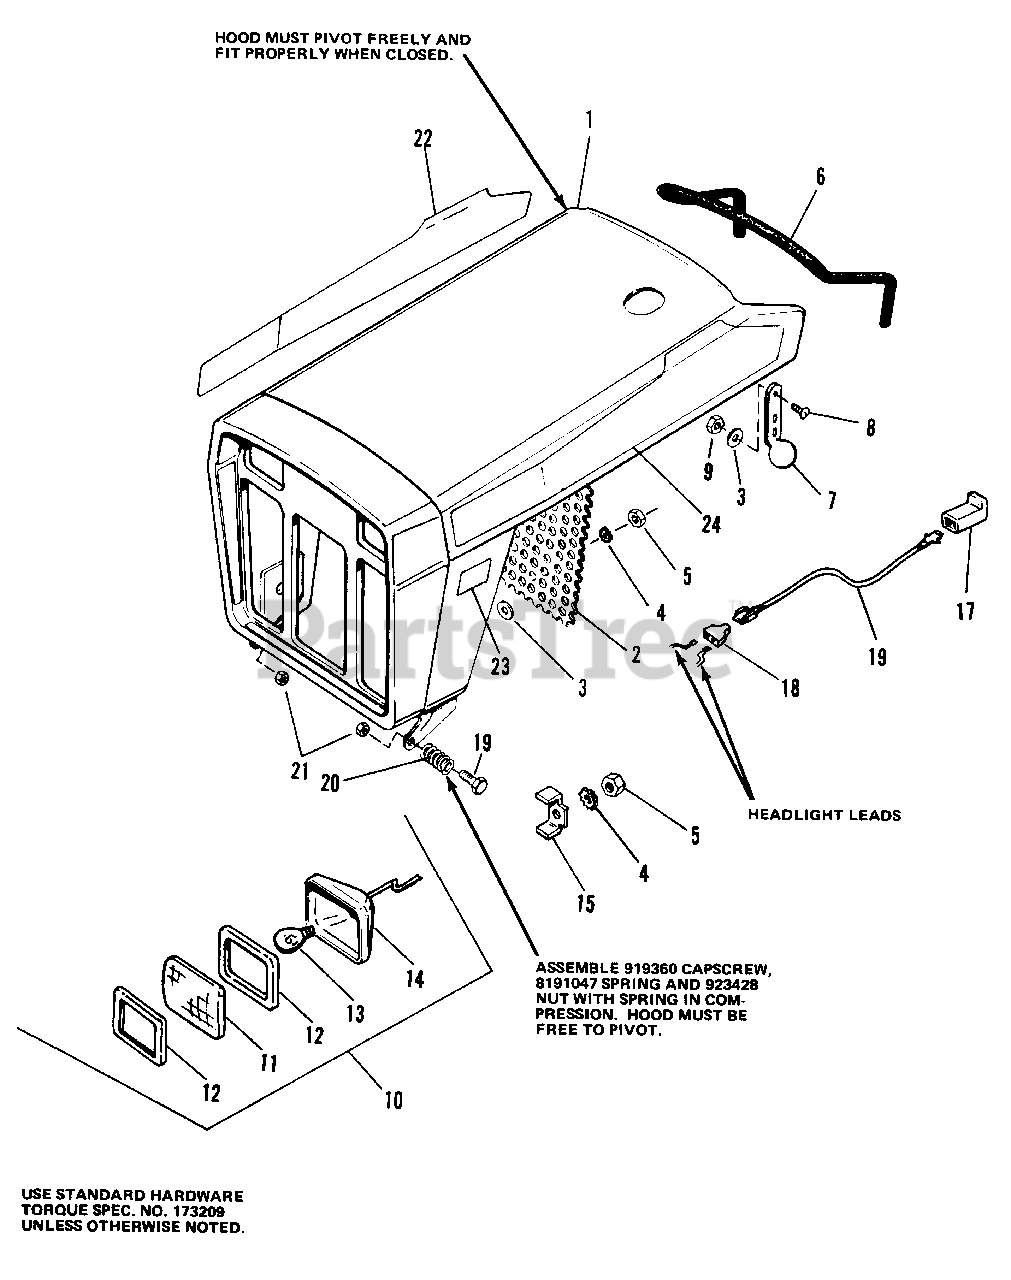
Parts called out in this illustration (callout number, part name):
1	HOOD & GRILLE ASSEMBLY
2	SCREEN, Grille
3	WASHER, Special
4	LOCKWASHER, Ext. Tooth, No. 10
5	NUT, Hex, Mach., No. 10-24
6	MOULDING Hood
7	STRAP, Hood
8	SCREW, Truss Hd., No. 10-32 x 1/2
9	LOCKNUT, Hex, No. 10-32
16	WIRE ASSY
17	BODY, Connector
18	CONNECTOR, Insulated
19	CAPSCREW, Hex,Hd., 3/8-16 x 1-1/2
21	NUT, Hex, 3/8-16
22	DECAL, Hood, Baron, R.H.
23	DECAL, 7013-Shuttle
24	DECAL, Hood, Baron, L.H.
